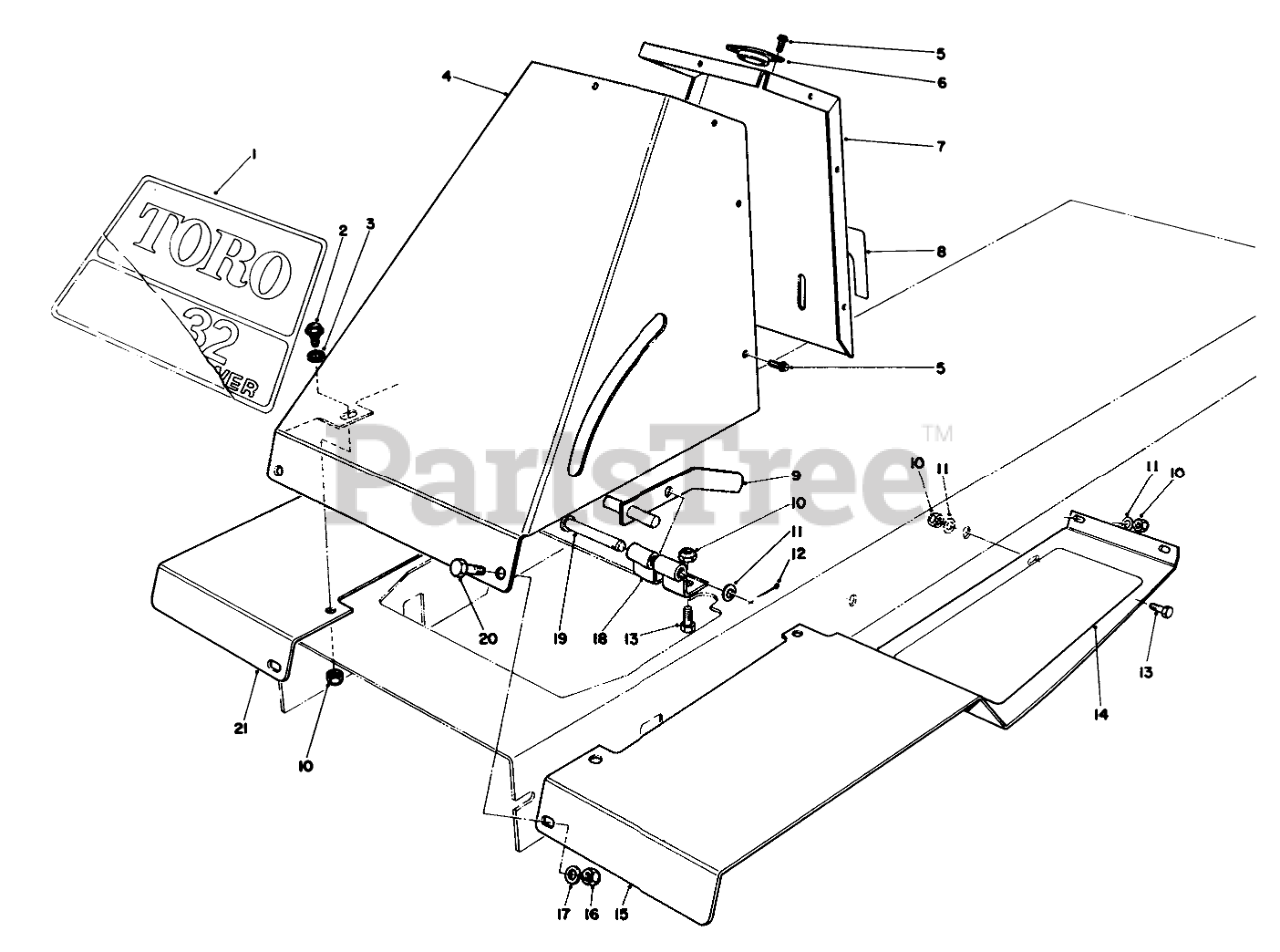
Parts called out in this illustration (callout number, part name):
1	Decal-Toro 832
2	SCREW-SHOULDER
3	SPACER
4	Tower-Front
5	SCREW-HWHTF
6	GUIDE-STRG SHAFT
7	Tower-Rear
8	PARK BRAKE DECAL
9	PARKING BRAKE WA B
10	NUT-LOCK, NI
11	WASHER-PLAIN
12	PIN-COTTER
13	SCREW-HH
14	FOOT TREAD L.H.
15	Footrest-LH
17	WASHER-FLAT
18	Bracket-Parking Brake
19	PIN-CLEVIS
20	SCREW-HH
21	Footrest-RH.
